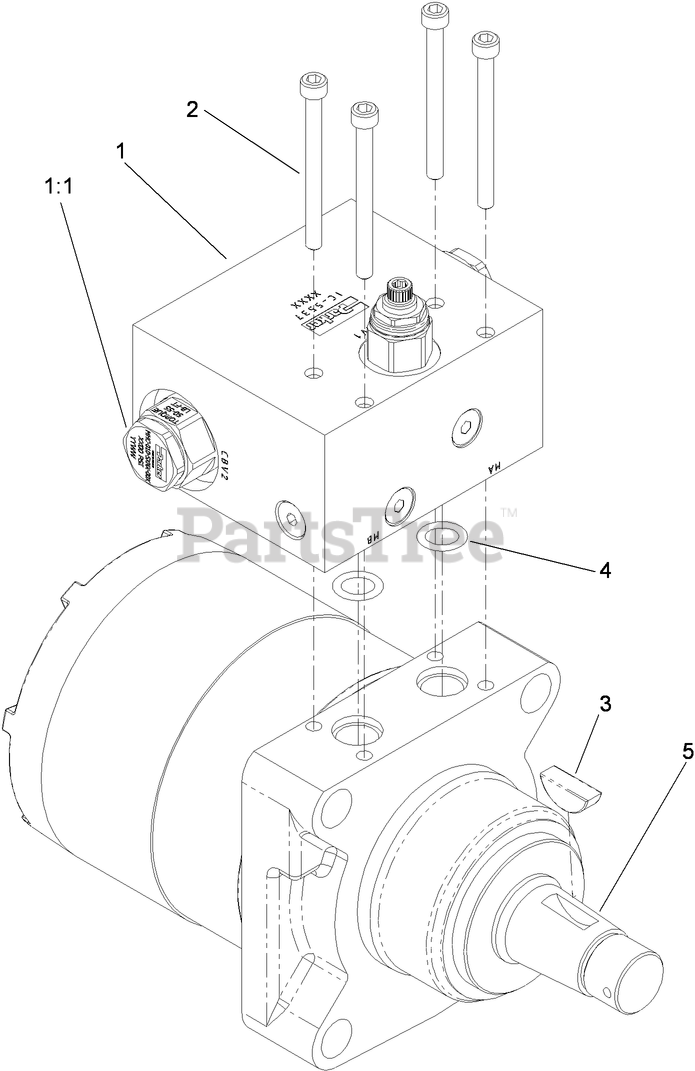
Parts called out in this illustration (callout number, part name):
1	COUNTERBALANCE VALVE ASM
1:1	VALVE-CARTRIDGE
2	BOLT-HSH
3	KEY-WOODRUFF
4	O-RING
5	SHAFT-COUPLING
